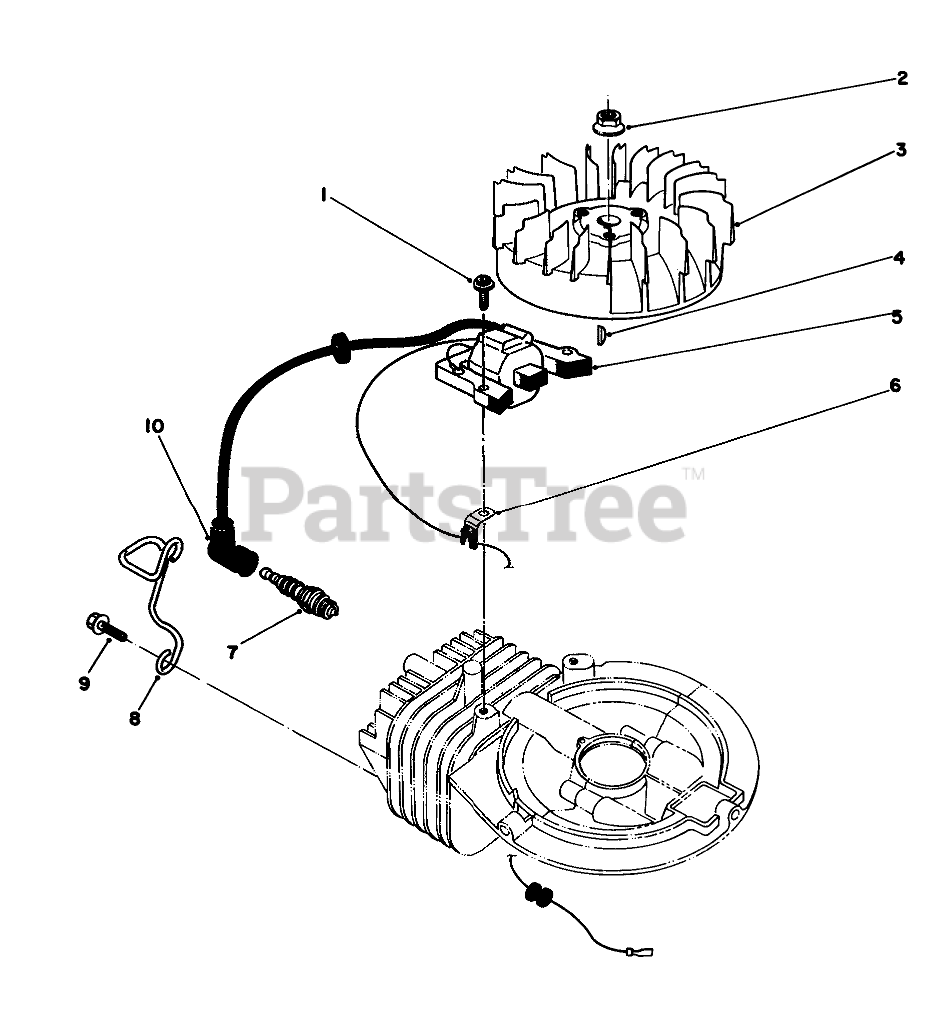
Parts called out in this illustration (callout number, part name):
1	SCREW
3	FLYWHEEL
5	COIL-MAGNETO
6	CLAMP
7	Sparkplug
8	PROTECTOR-PLUG
9	SCREW
10	CAP-SPARKPLUG
